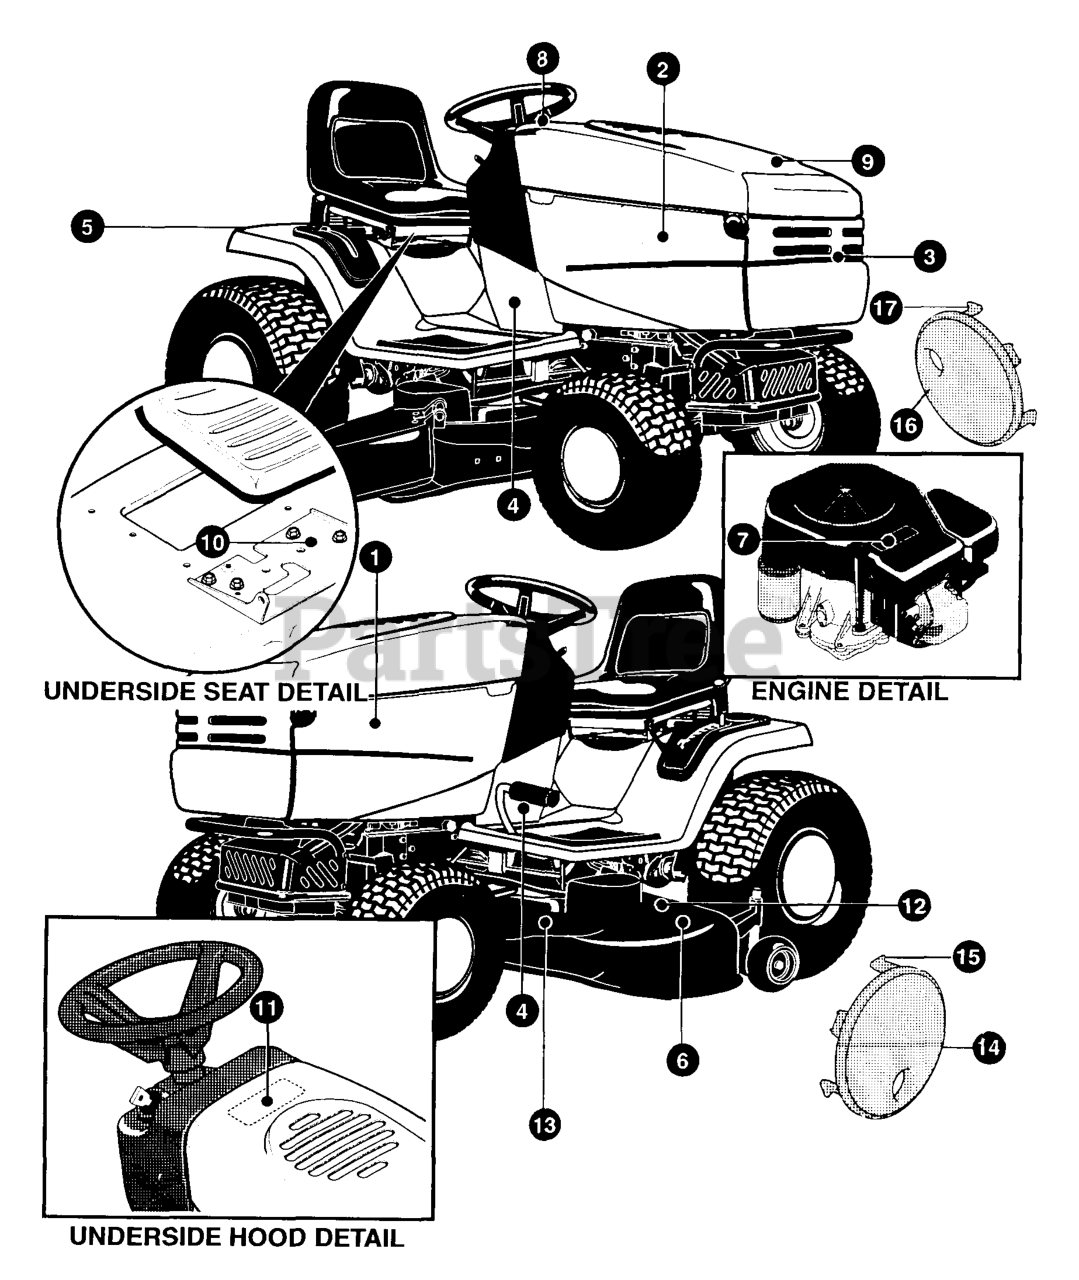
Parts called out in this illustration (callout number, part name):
1	DECAL, SCOTTS 16/42 RH
2	DECAL, SCOTTS 16/42 LH
3	DECAL, PIN STRIPE SCOTTS
4	DECAL, KO OIL FILTRATION SYSTEM
5	DECAL, SCOTTS S/D REAR
6	DECAL, CUTTING DECK
7	DECAL, SCOTTS 16HP KOHLER
8	DECAL, CUST. CARE CENTER
9	DECAL, EMBLEM HOOD SCOTTS
10	REFERENCE ONLY
11	DECAL, MAINTENANCE 16HP KOHLER
12	DECAL, DECK LEVEL PROCEDURES
13	DECAL, DECK ROUTING
14	HUB CAP 8" W/O HOLE
15	CLIP, HUBCAP TINN #C25467-017-4
16	HUB CAP 6" W/O HOLE
17	CLIP, HUBCAP TINN #C25467-017-4
